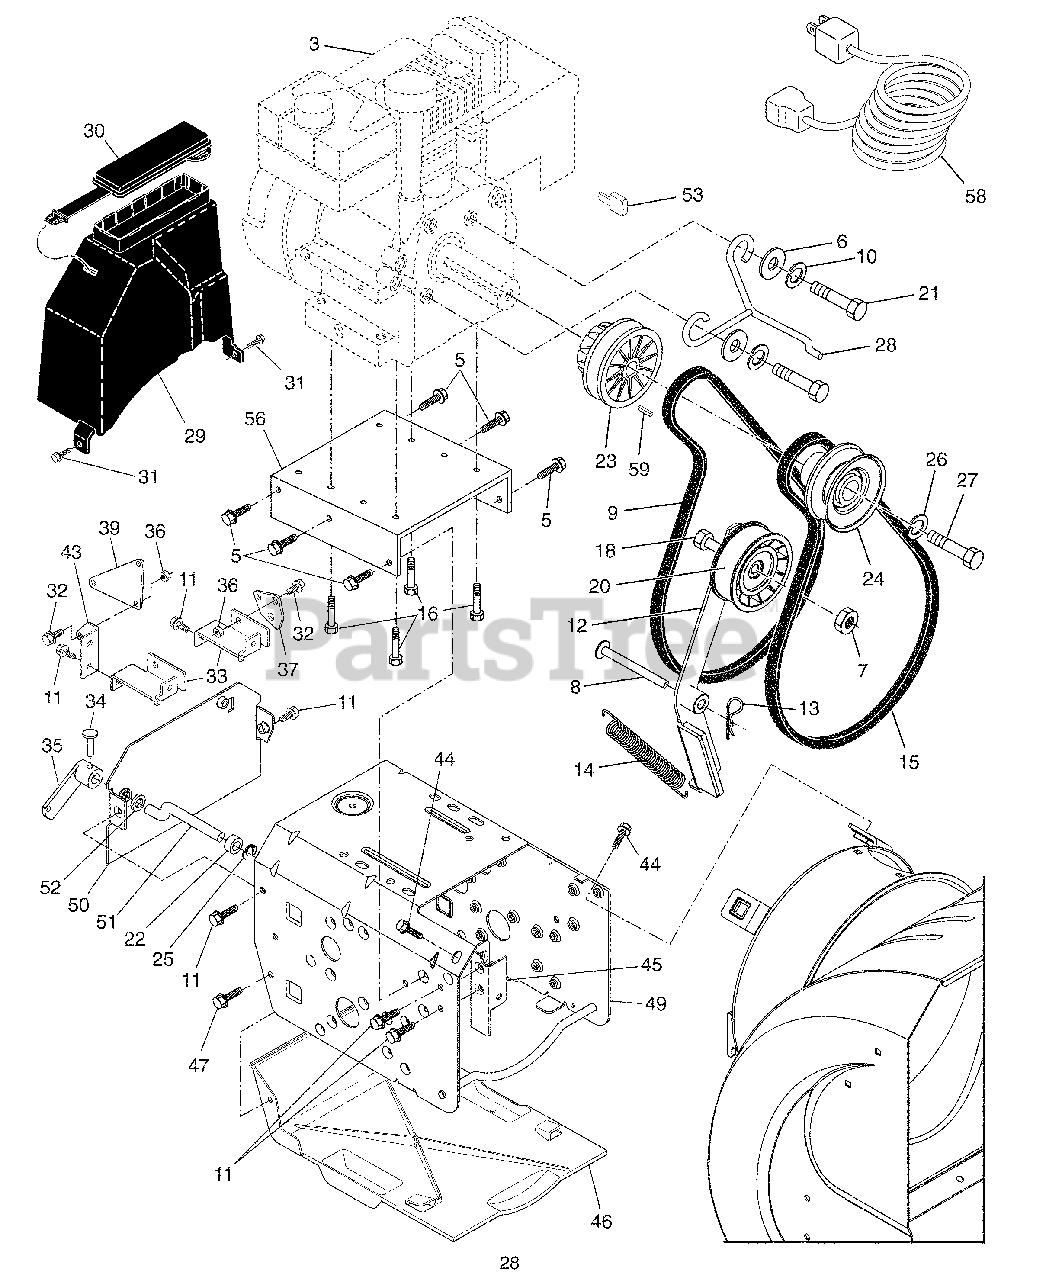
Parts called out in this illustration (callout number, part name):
6	Washer, Flat
7	Nut, Jam, Lock 5/16-18
8	Pin, Idler Pivot
9	Belt, Traction Variator
10	Washer, Lock 5/16
11	Screw, Hex Head 5/16-18 x 1/2
12	Idler Arm / Brake Pad Assembly
13	Retainer, Hairpin
14	Spring, Brake
15	Belt, Impeller Drive
16	Screw, Hex Head 3/8-16 x 1-1/4
18	Screw, Hex Head 5/16-18 x 1-1/2
20	Pulley, Idler (2-3/4)
21	Screw, Hex Head 5/16-18 x 1
22	Roller, Actuator
23	Pulley, Engine, Variator
24	Pulley, Engine, Impeller Drive
25	Ring, Crescent
26	Washer, Lock 3/8
27	Screw, Hex Head 3/8-24 x 1-3/8
28	Guide, Belt
29	Belt Cover Assembly
30	Cover, Toolbox
31	Screw, Hex Head 1/4-20 x 1/2
32	Bolt, Shoulder
33	Bracket, Cable, Rear
34	Clevis Pin
35	Arm, Auger Control
37	Plate, Clutch
39	Plate, Speed, Pivot
43	Bracket, Speed, Pivot
44	Screw, Hex Head
45	Bracket, Pivot, Idler
46	Pan, Frame Bottom
47	Screw, Hex Head 5/16-18 x 3/4
49	Frame Assembly
50	Plate, Frame End
51	Shaft, Auger Control
52	Washer, Hardened
53	Key, Safety
56	Mounting Plate, Engine
58	Power Cord
59	Key, Square, Variator Pulley
